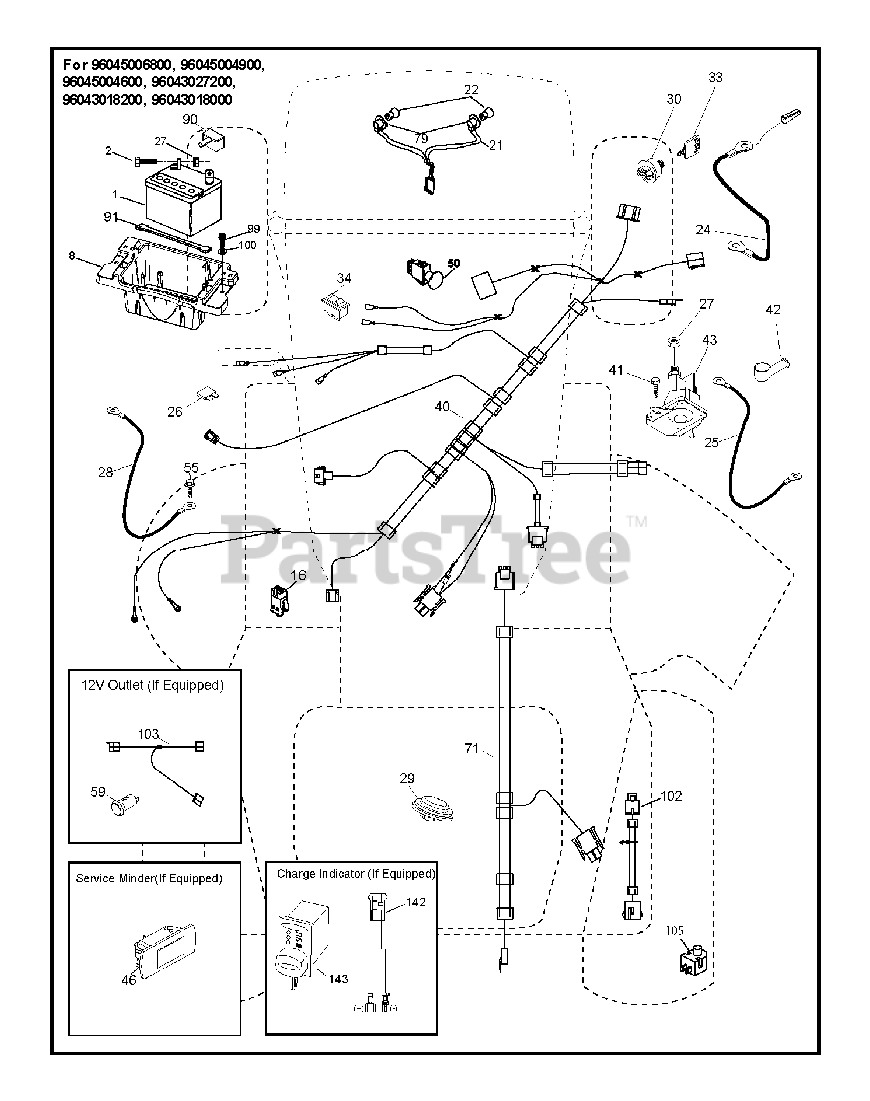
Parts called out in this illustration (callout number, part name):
1	Battery 12 Volt 25 Amp
2	BOLT.HEX.1/4.X.3/4.DICHROMATE
8	BOX.BATTERY.MOUNT.FRONT.LT
8	TRAY.ASM.BATTERY.FRT.TEX.CARB
8	TRAY.BATTERY BOX.FRONT
16	SWITCH INTERLOOK PUSH-IN
21	HARNESS ASSY LIGHT
21	HARNESS.LIGHT W/4152J BULBS
24	CABLE.FRBATT.W/WIRE.8GA.8
25	CABLE.STARTER.8GA.17.5
26	FUSE 20AMP
27	NUT HEX_LRG FLG_1_4-20_LOCK
28	CABLE.GROUND.21"BLK.8GA.90T
28	CABLE GROUND 6 GA 21" 90T BLK
29	SWITCH.SEAT.DELTA.OPC.
30	SWITCH.IGN.DELTA.W.LGH.ROS
33	KEY.CHAIN.BLISTER.PACK.GEN.INT
33	KEY.CHAIN.BLISTER.PACK.GEN.USA
40	HARNESS.IGN.DASH.HUQ/P
40	HARNESS HARNESS..DASH.ING.ELEC
40	HARNESS.TEX.DASH.ELEC.REAR BAT
41	SCREW
42	TERMINAL COVER
46	GUAGE.SRVCMNDR.HRMTR.
46	RP.GUAGE.SRVCMNDR.HRMTR.
50	RP SWITCH.PTO.TERMINAL.STD.RED
55	SCREW 5/16"
71	HARNESS-CHASSIS SUB
71	HARNESS.CHASSIS.RRBATT.RDYSTRT
79	BULB HOLDER ASM.
90	COVER.TERMINAL.BATTERY
91	STRAP.BATTERY.MOUNT.FRONT(2 2)
99	SCREW HEXWSHR 1/4-20X3/4
102	HARNESS PIGTAIL PCH TEX ROS
105	REVERSE SWITCH
